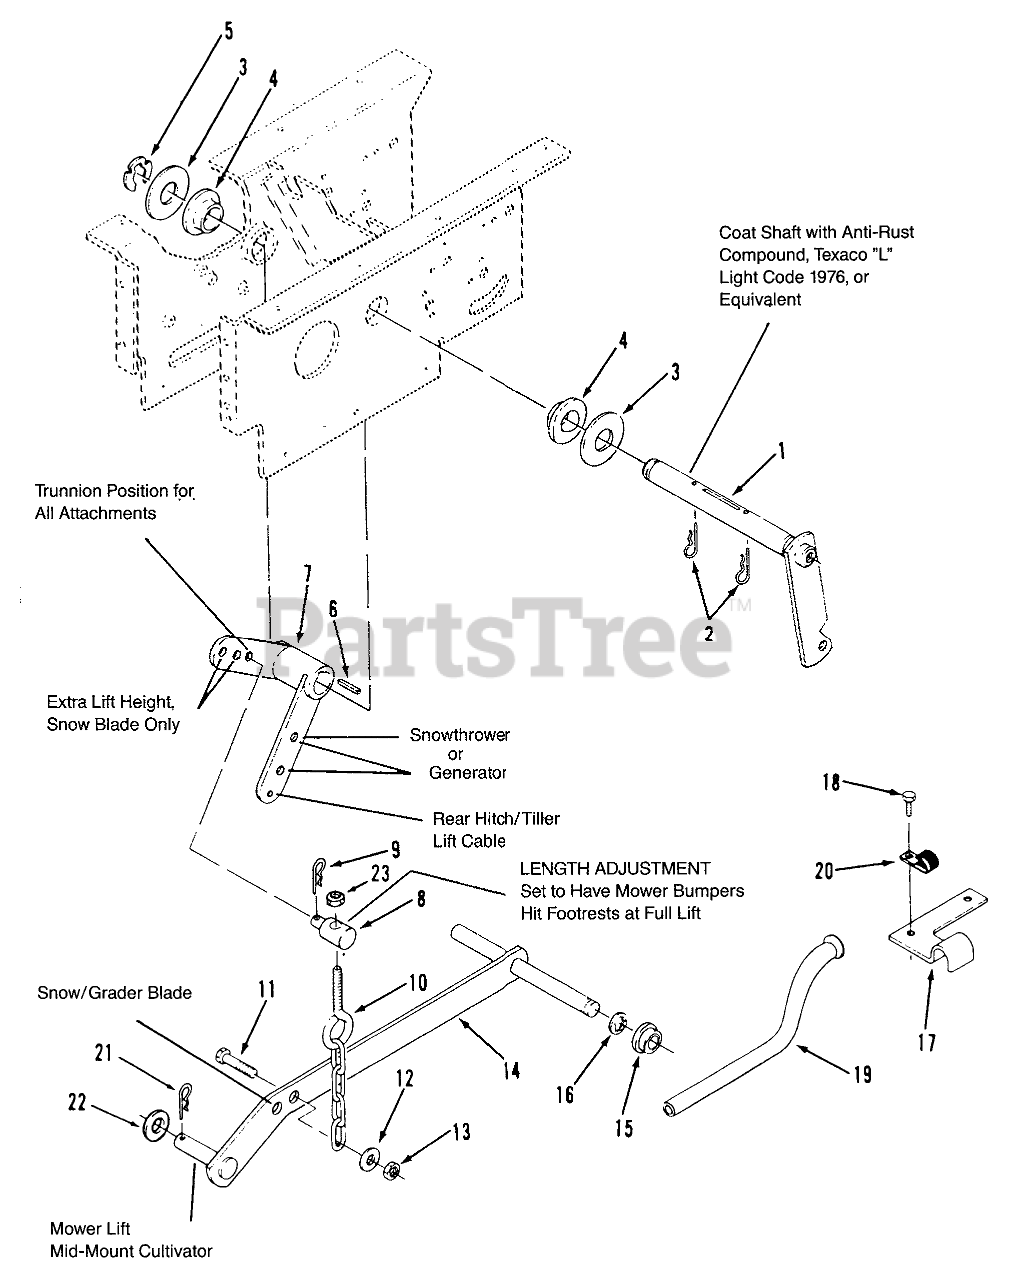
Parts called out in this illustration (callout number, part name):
1	WLDMT-LIFT ARM
2	Pin-Cotter
3	WASHER
4	BEARING-FLANGE
5	Retainer
6	KEY-SQUARE
7	Bellcrank
8	TRUNNION-LIFT
9	Hairpin Cotter
10	CHAIN-LIFT
11	Bolt
12	WASHER 5/16 SAE
13	Nut
14	Bar-Lift
15	BUSHING
16	E Ring
17	CLAMP-CONDUIT R
18	BOLT
19	TUBE-CONDUIT R
20	CLIP
21	Hairpin Cotter
22	Washer
23	NUT
